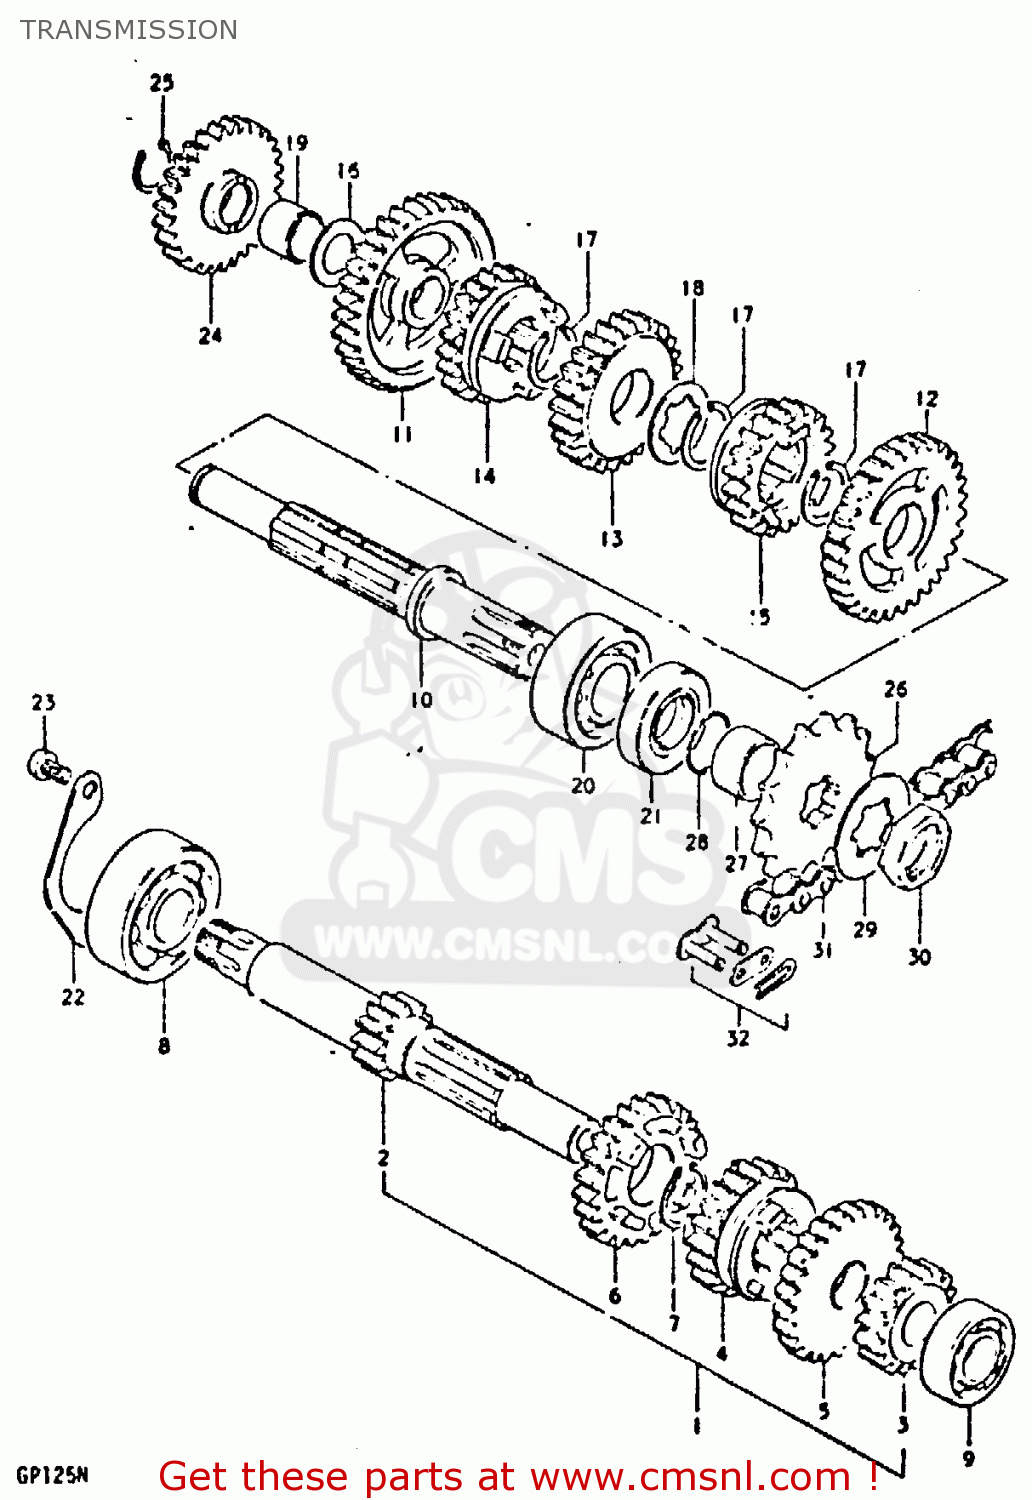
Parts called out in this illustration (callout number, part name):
1	SHAFT, COUNTER
2	COUNTER SHAFT (NT:11)
3	GEAR,SECOND DRIVE
4	GEAR, 3RD DRIVE (NT:20)
5	GEAR, 4TH DRIVE (NT:23)
6	GEAR, 5TH DRIVE (NT:25)
7	CIRCLIP
8	Bearing
9	BEARING
10	SHAFT, DRIVE
11	GEAR,1ST DRIVEN
12	GEAR, 2ND DRIVEN (NT:29)
13	GEAR, 2ND DRIVEN (NT:29)
14	GEAR, 4TH DRIVEN (NT:22)
15	GEAR, 5TH DRIVEN (NT:20)
16	WASHER,THRUST
17	CIRCLIP
18	WASHER
19	BUSH
20	Bearing
21	SEAL,OIL(25X40X7)
22	RETAINER,CNTR SHAFT BEARING
23	SCREW 6X12
24	GEAR,KICK STARTER IDLE
25	CIRCLIP,15MM
26	SPROCKET,ENGINE
27	SPACER(20X25X12.5)
28	O RING(D:1,ID:19.5)
29	WASHER,LOCK
30	NUT
31	CHAIN ASSEMBLY,DRIVE
32	JOINT ASSEMBLY,CHAIN
